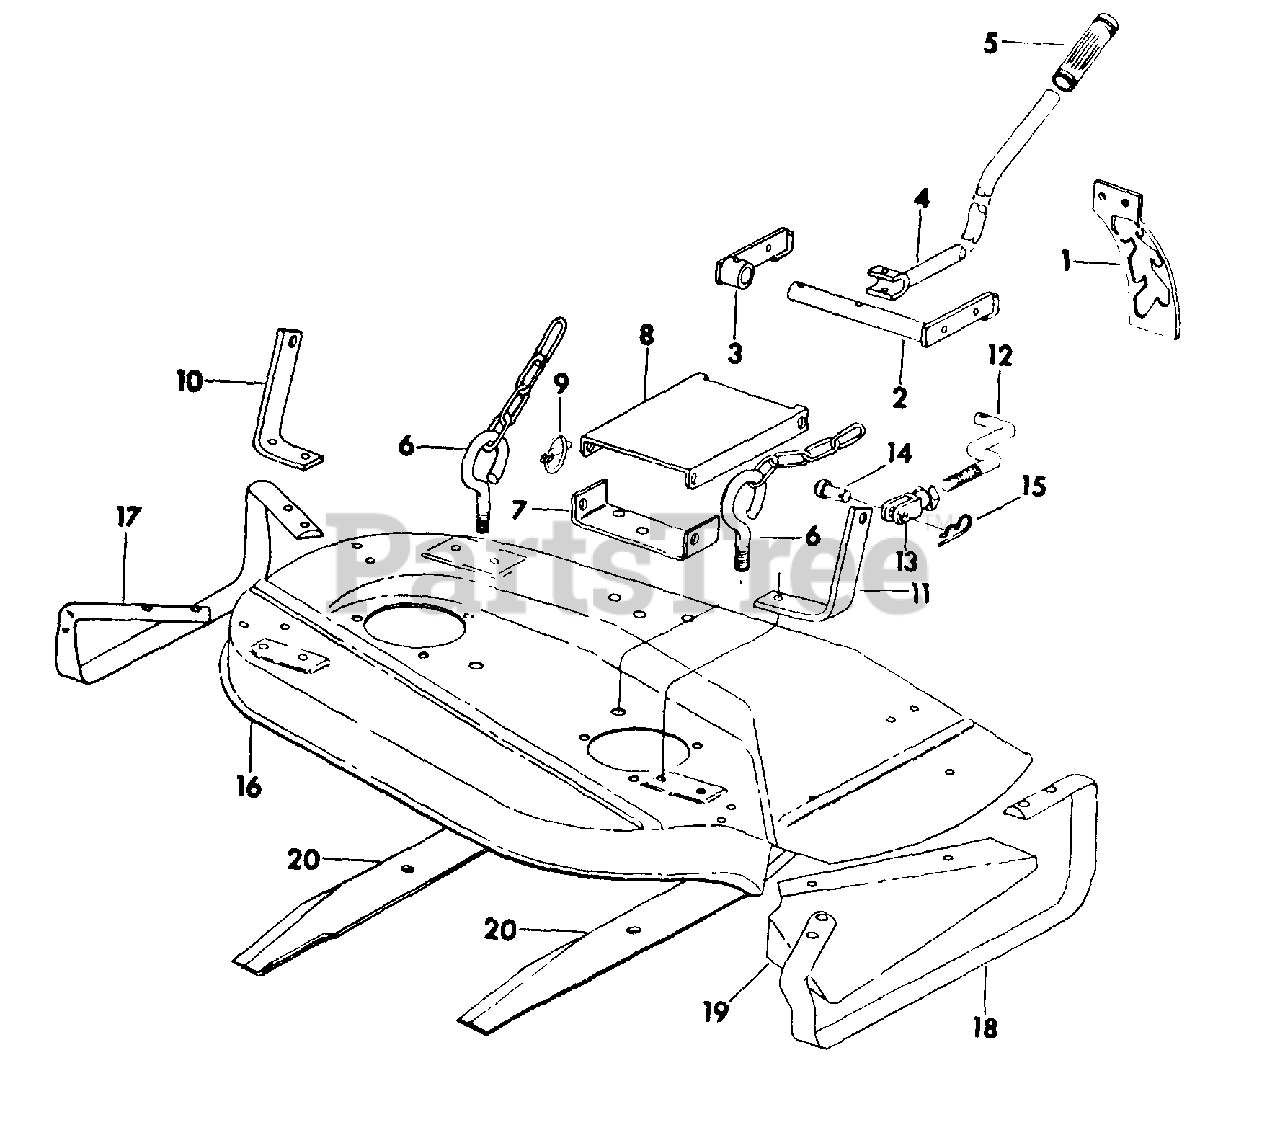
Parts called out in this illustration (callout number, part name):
1	SECTOR, LIFT HANDLE
2	SHAFT ASSY, MOWER LIFT
3	ARM ASSY, MOWER LIFT
4	HANDLE ASSY. LIFT
5	GRIP, LIFT HANDLE
6	CHAIN ASSY, MOWER
7	BRACKET, MOWER FRONT
8	LINK, MOWER FRONT
9	PIN, KLIK
10	BRACKET, REAR LINK - LH
11	BRACKET, REAR LINK - RH
12	LINK, LIFT REAR
13	CLEVIS, 1/2 SHORT ADJUSTABLE ROD END
14	PIN, 1/2 X 1-27/64 ROD END
15	PIN, SPRING
16	HOUSING W/PRODUCT GRAPHICS, MOWER
17	RUNNER, LH MOWER
18	RUNNER, RH MOWER
19	SHIELD, DEFLECTOR
20	BLADE, 32 IN CUTTING
